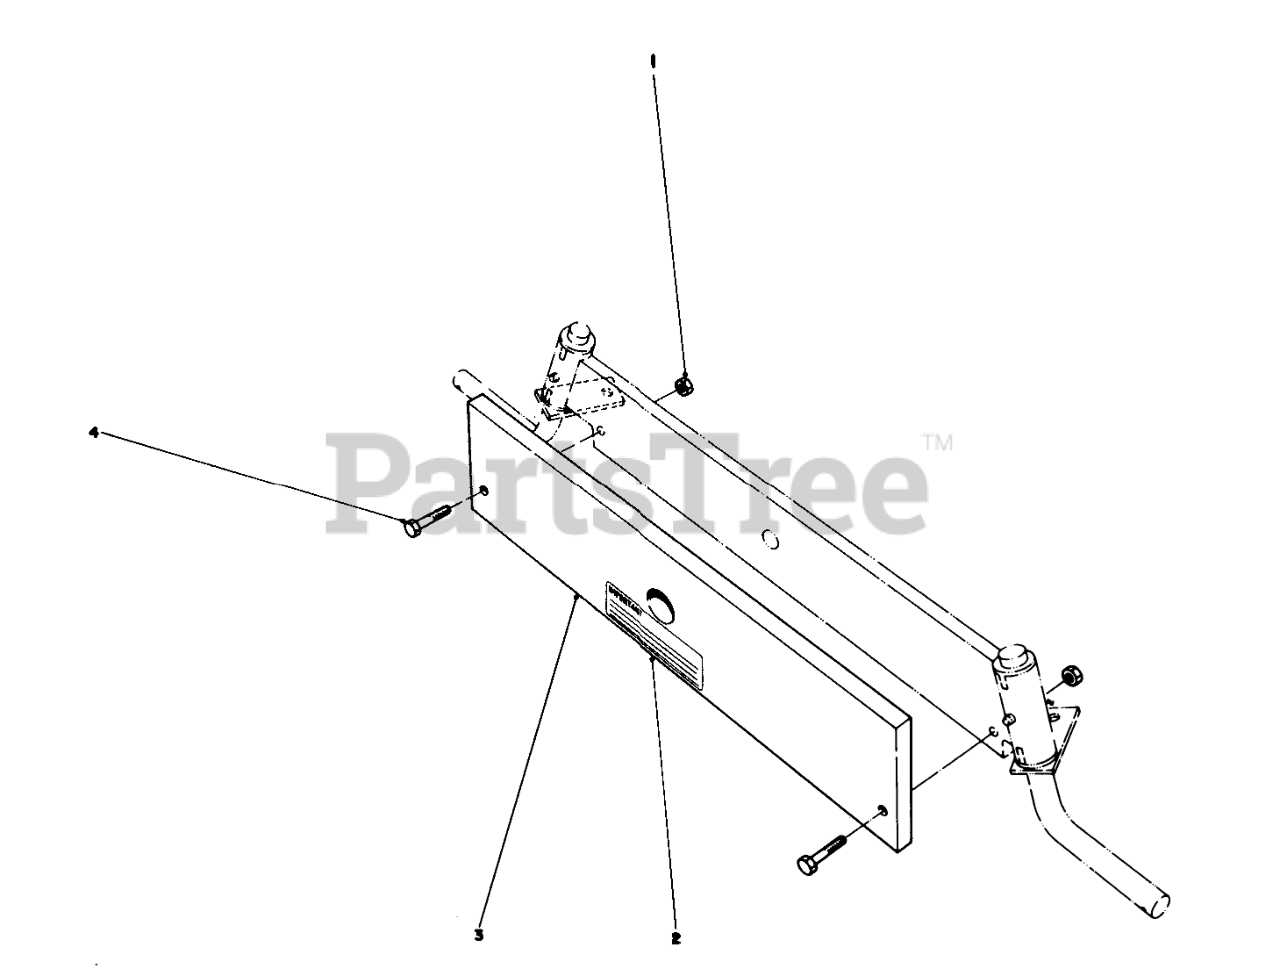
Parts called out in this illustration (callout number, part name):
1	NUT-LOCK, CONE
2	Decal-Warning
3	COUNTERWEIGHT B
4	SCREW-HH
